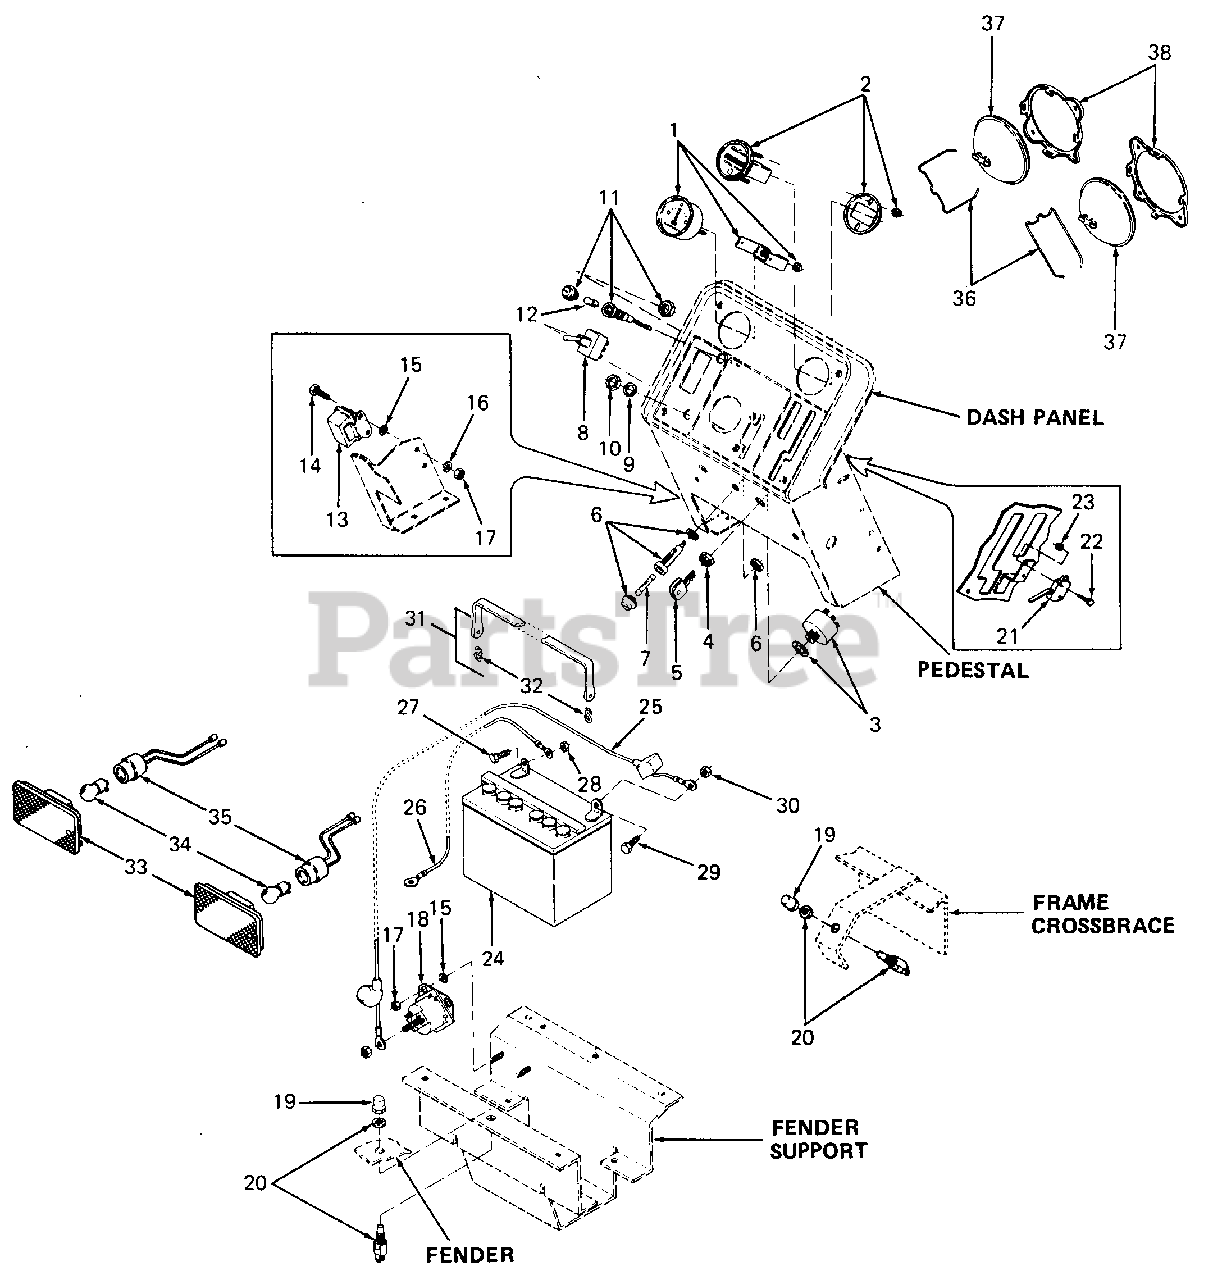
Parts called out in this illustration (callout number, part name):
1	Ammeter
2	Hourmeter
3	Switch, Ignition Key
4	Nut, Switch
5	Key, Ignition (Set of 2)
6	Fuse Holder
7	Fuse, 20 Amp Slo-Blo
8	Switch, PTO
9	Washer, Flat, .531 X .680 X .054 Thk
10	Nut, Hex, 1/2-27 X .100 Thk
11	Light Assy, Oil Indicator
12	Bulb, Light
13	Relay
14	Screw, Hex Cap, 1/4-20 X .62 Lg GR5
15	Washer, Ext Lock, 1/4
16	Washer, Lock, 1/4
17	Nut, Hex, 1/4-20 GR5
18	Solenoid
19	Boot, Switch
20	Switch w/Nut
21	Switch, Reverse
22	Screw, Hex Mach, #4-40 X .75 Lg
23	Nut, Hex Insert Lock, #4-40
24	Battery
25	Cable, Positive Battery
26	Cable, Negative Battery
27	Bolt, Carriage, 1/4-20 X .75 Lg
28	Nut, Hex, 1/4-20 GR5
29	Bolt, Carriage, 5/16-18 X .75 Lg
30	Nut, Hex, 5/16-18 GR5
31	Strap Assy, Battery
32	Hook, Battery Strap
33	Lens Assy, Tail Light
34	Bulb, Light
35	Cable Assy, Tail Light
36	Spring, Headlight Retaining
37	Headlight
38	Retainer, Headlight
